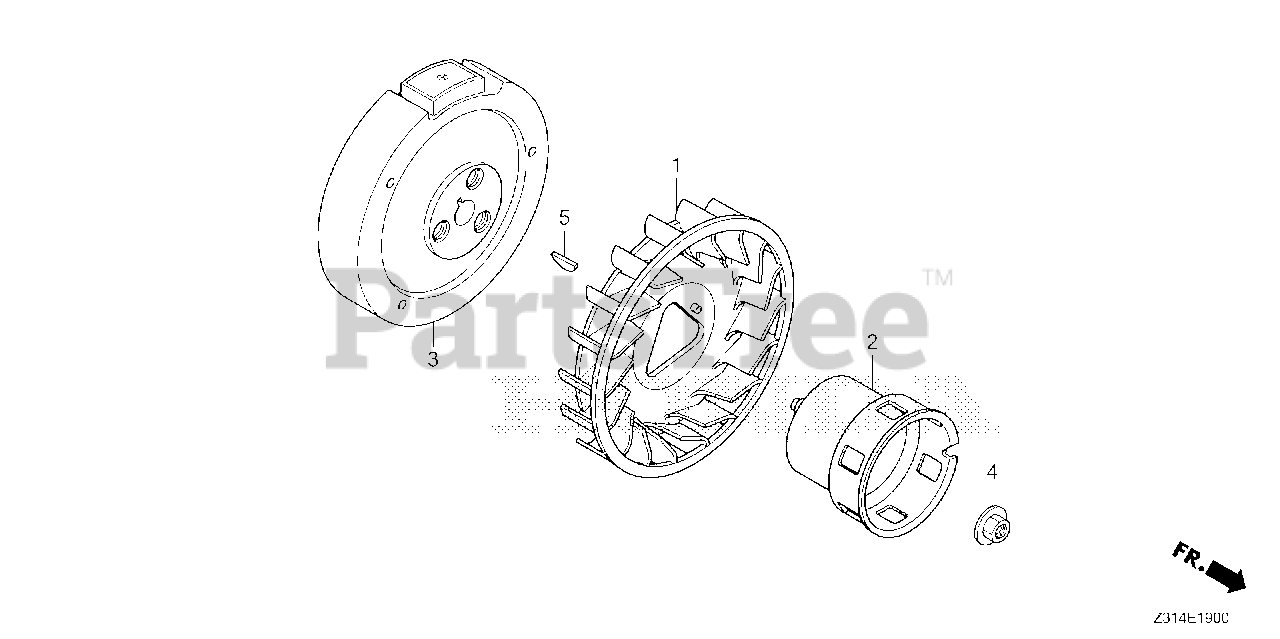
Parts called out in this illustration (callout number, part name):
1	FAN, COOLING
2	PULLEY, STARTER
3	FLYWHEEL (LAMP)
4	NUT, SPECIAL (16MM) (1)
5	KEY, SPECIAL WOODRUFF (25X18)
